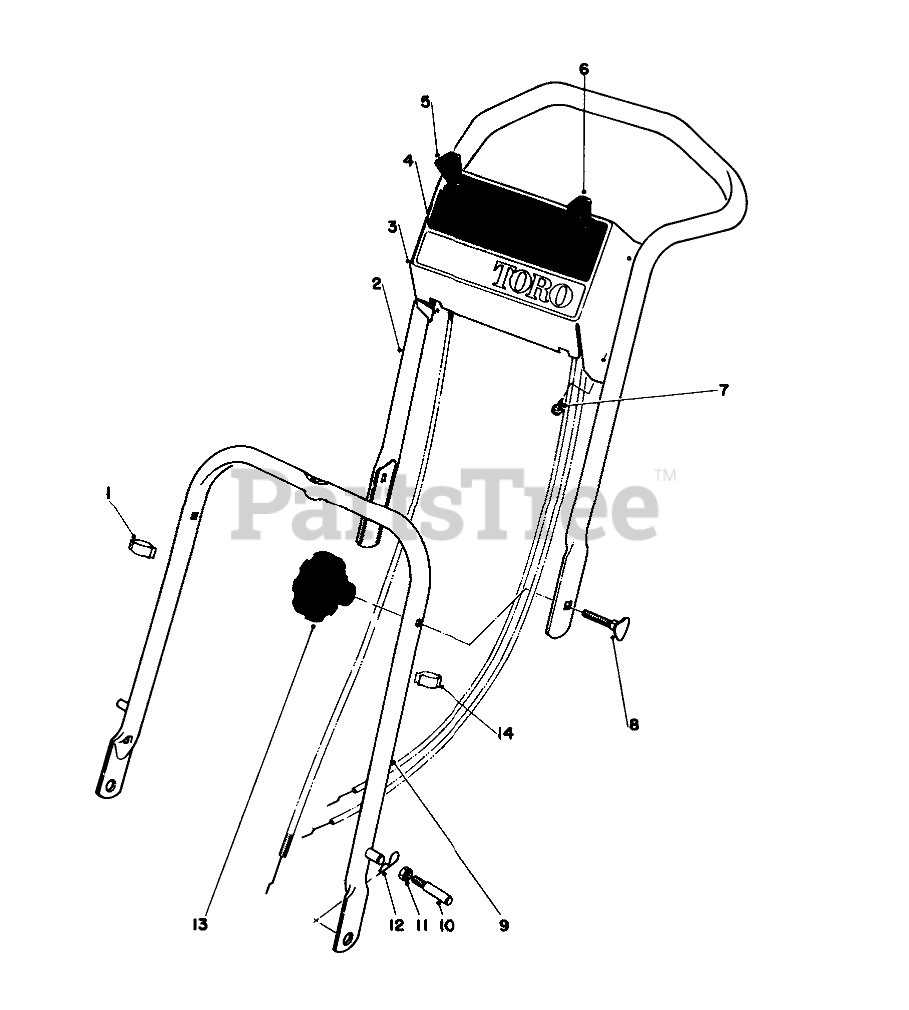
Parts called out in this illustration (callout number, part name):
2	UPPER HANDLE
3	Control Plate (Incl. Ref. #4)
4	Decal-Control Plate
5	Throttle Control
6	Traction Control
7	SCREW-HWHTF
8	SCREW-HANDLE
9	LOWER HANDLE ASM
10	HANDLE PIN
11	Nut
12	PIN-COTTER, HAIR
14	BOWDEN CLIP
